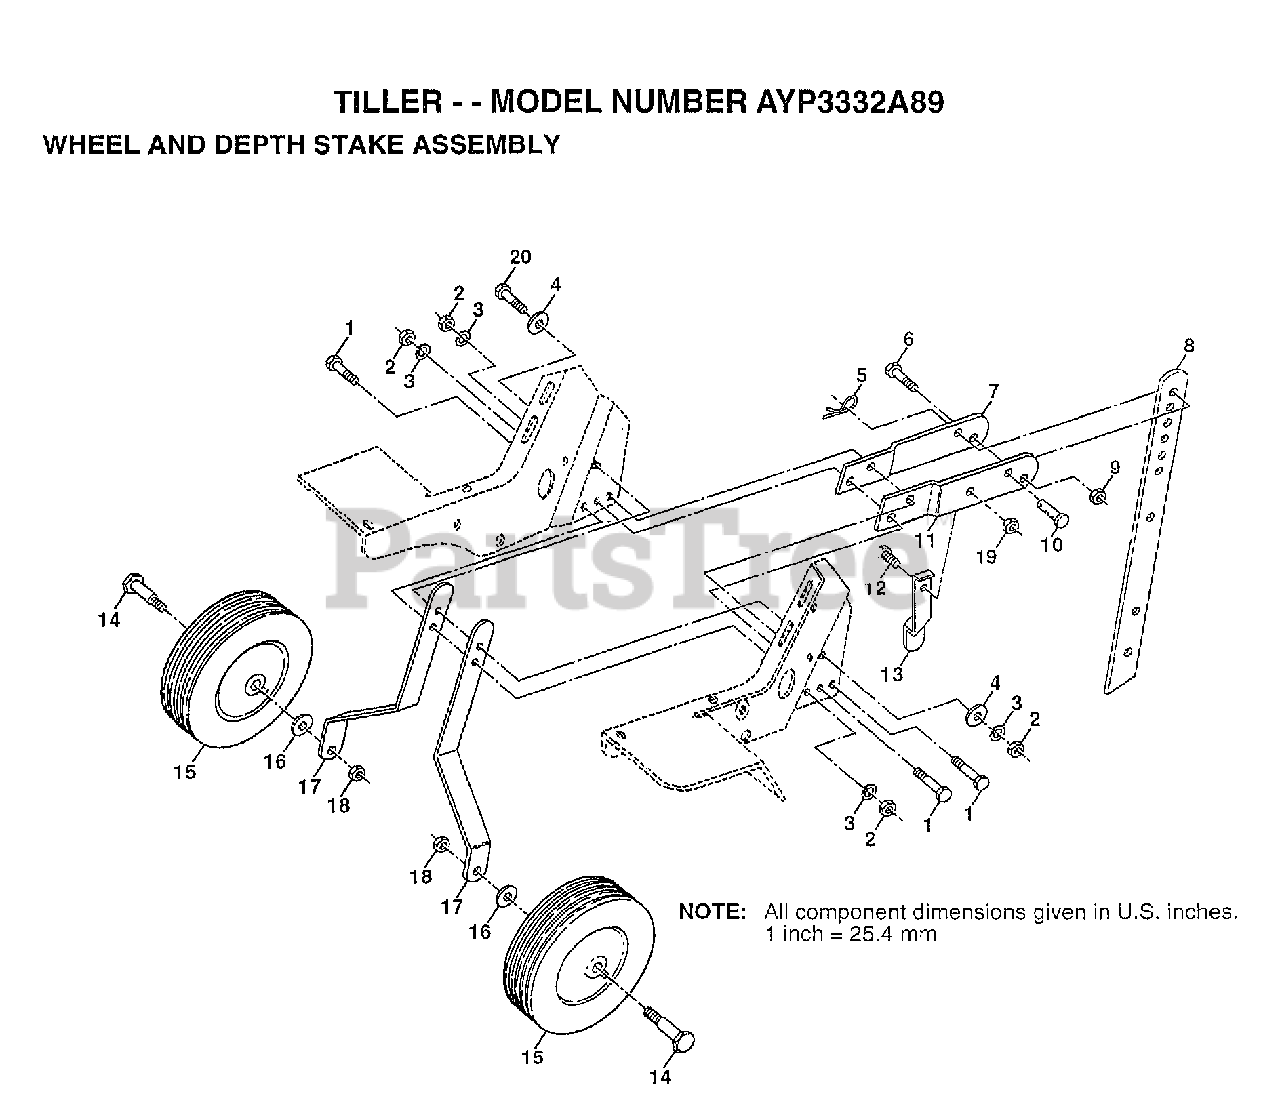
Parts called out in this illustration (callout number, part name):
2	NUT.HEX.5/16-18
3	LOCKWASHER
4	WASHER
6	BOLT
7	STAKE.SUPT.TILLER
9	NUT
10	DRILLED RIVET RT
12	BOLT
13	STAKE SPRING CT
14	BOLT SHOULDER
16	WASHER
19	NUT
20	BOLT.HEX.5/16-1.5
